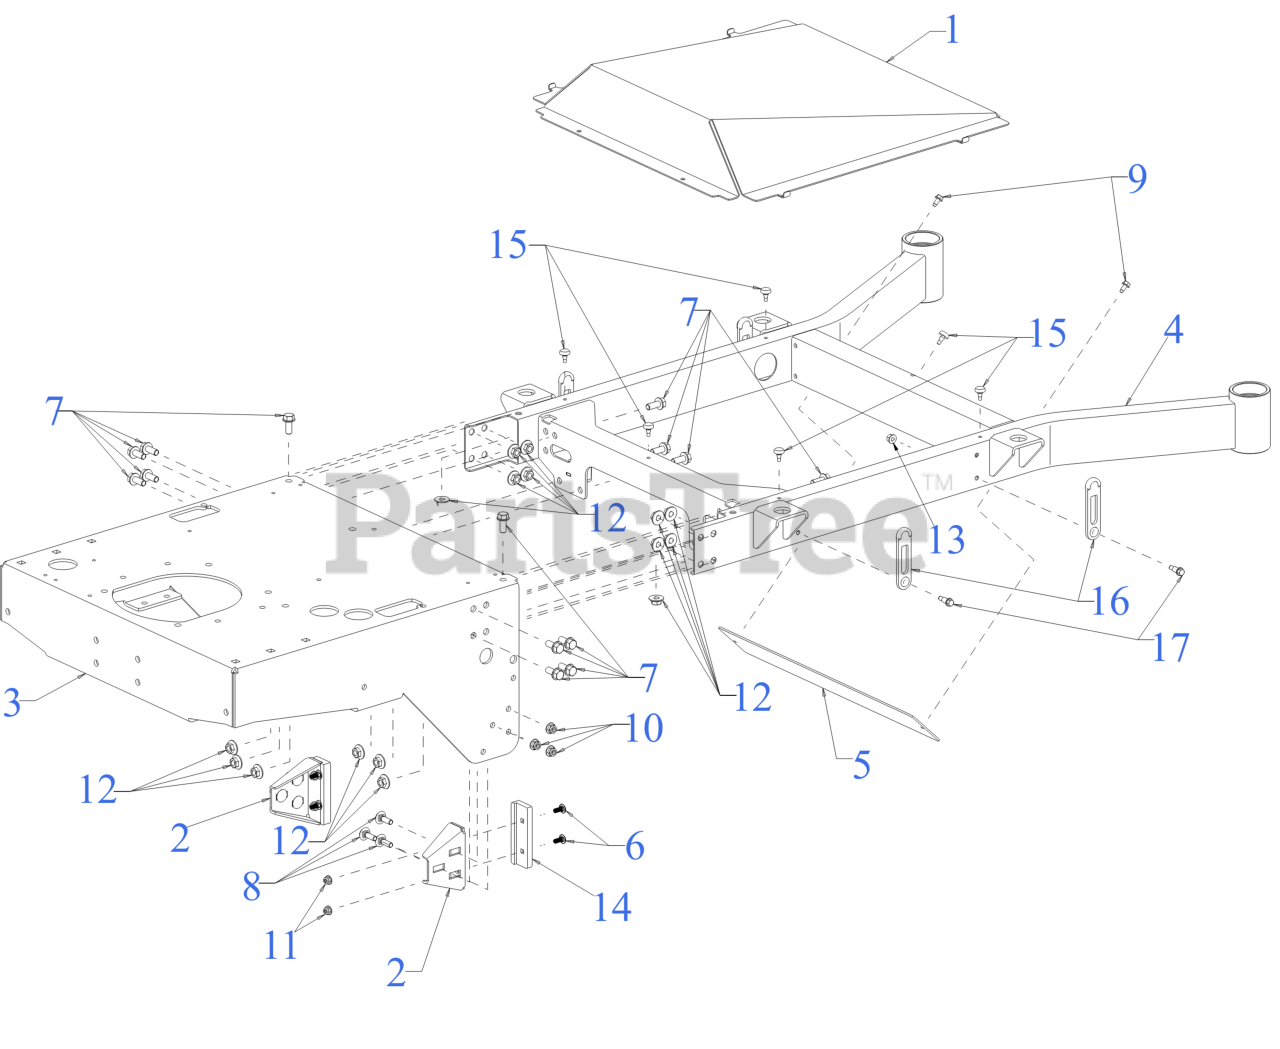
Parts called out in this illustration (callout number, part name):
1	DECK COVER ASSEMBLY (CUB YELLOW 2)
3	FRAME
4	FRONT FRAME ASSEMBLY
6	CARRIAGE BOLT 1/4-20 x .62
7	SCREW 3/8-16 x .875 GR5
8	SCREW 5/16-18 x 1.00 GR5
9	SCREW 1/4-20 X.500
10	FLANGE LOCK NUT 5/16-18
11	FLANGE LOCK NUT
12	FLANGE LOCK NUT
14	BUMPER PAD
15	RUBBER BUMPER
16	COVER STRAP 2.50 LONG
17	SHOULDER SCREW
